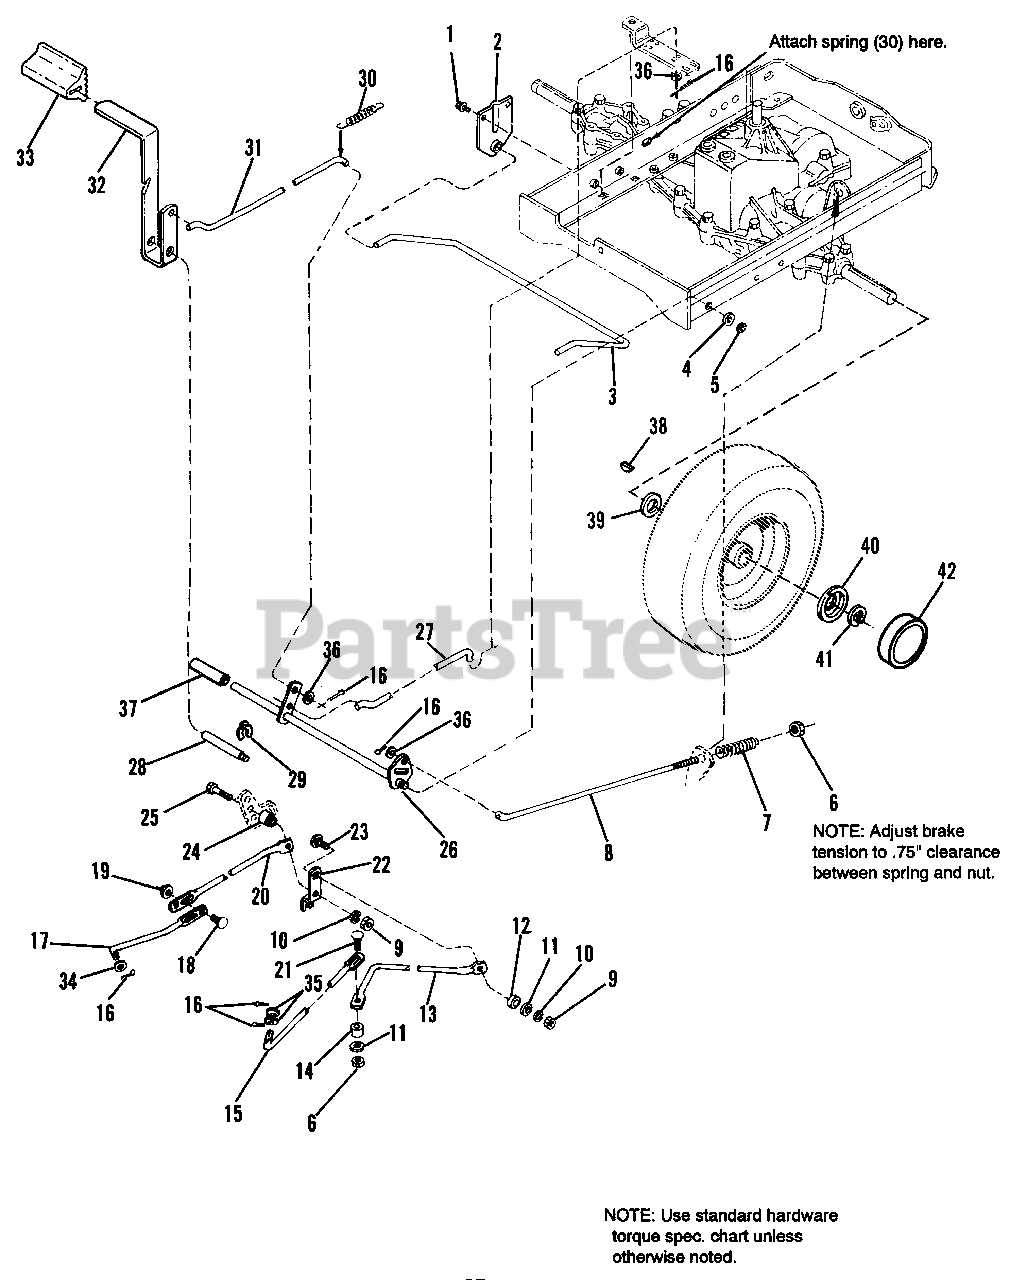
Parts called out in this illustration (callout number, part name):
1	SCREW, Taptite, 5/16-18 x 1/2
2	BRACKET, Torsion Bar
3	TORSION BAR
4	WASHER, Plain
5	KLIPRING, 1/2
6	NUT, Hex, Lock, 5/16-18
7	SPRING, Compression
9	NUT, Hex, 5/16-18
10	LOCKWASHER, 5/16
11	WASHER, Plain, 5/16
13	ROD, Control
14	SPACER
15	ROD, Shift, Front
16	COTTER PIN, 7/64 x 3/4
17	ROD, Return, Front
18	CARRIAGE BOLT, 1/4-20 x 7/8
19	NUT, Hex, Flange Whiz, 1/4-20
20	ROD, Return, Rear
21	CARRIAGE BOLT, 5/16-18 x 1-1/4
22	LEVER, Control
23	CARRIAGE BOLT, 5/16-18 x 1
25	CAPSCREW, 5/16-18 x 1-3/4
26	PIVOT SHAFT ASSY.
27	ROD, Clutch, Rear
28	PIVOT, Brake
29	KLIPRING, 3/4
30	SPRING, Return
31	ROD, Clutch, Front
32	LEVER, Clutch
33	PAD, Pedal
34	WASHER, Plain, 13/32 x 7/8 x 5/64
35	WASHER, Plain, 1/2 x 1 x 1/32
36	WASHER, Plain
38	KEY
39	WASHER, 3/4
40	RETAINER, Hubcap
